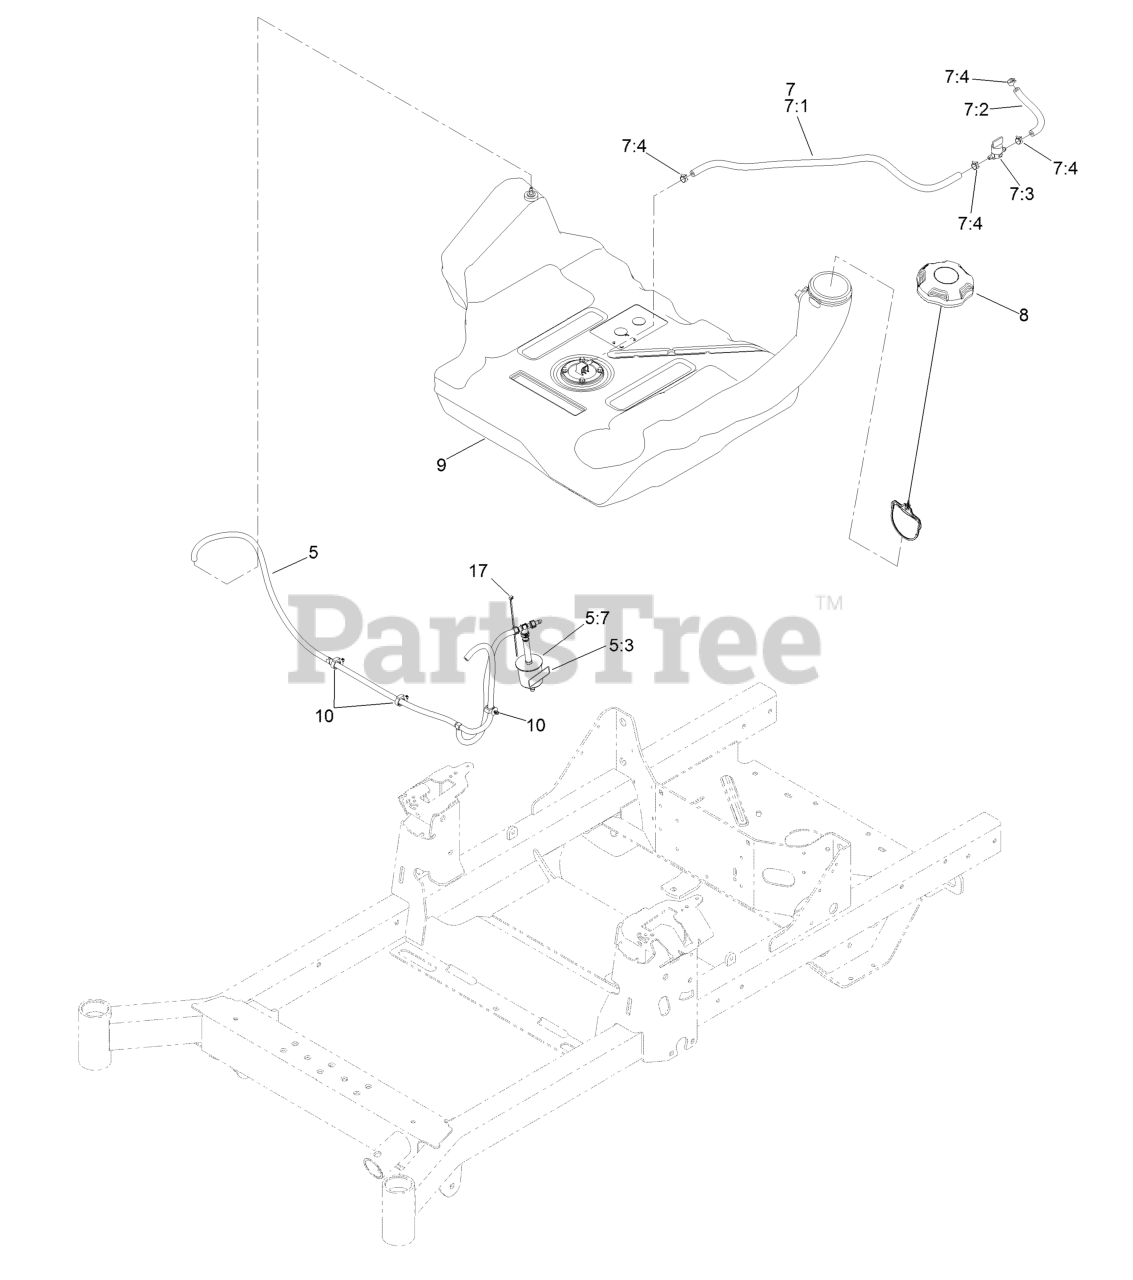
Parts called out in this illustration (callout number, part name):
5	Vent Hose ASM
5:3	Decal-Filter, Emissions
5:7	Filter-Fuel
7	Fuel Hose ASM
7:1	Hose-Fuel
7:2	Hose-Fuel
7:3	Valve-Fuel
7:4	Clamp-Hose
8	Cap-Fuel
9	Tank-Fuel
17	Tie-Cable
